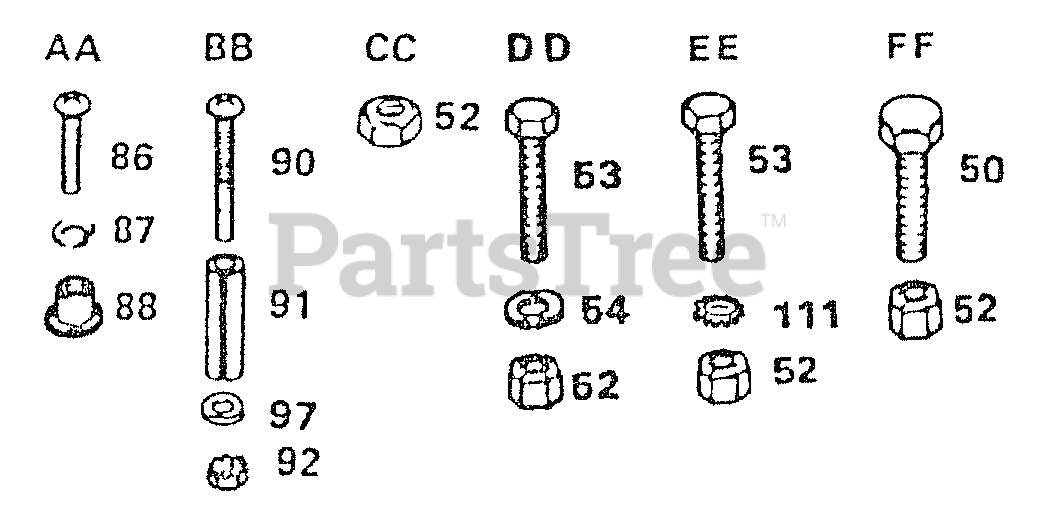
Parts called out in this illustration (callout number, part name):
50	Bolt - Hex 3/8 -16 x 3/4
52	Nut - Crownlock 3/8 - 16
53	Bolt- Hex 3/8 - 16 x 1
54	Washer 13/32 X 1 X 16 Ga.
86	Screw - Cross Recess Pan Hd. Machine 10-24 x 1/2
87	Washer- Lock, No. 10
88	Nut - Weld
90	Screw - Machine Cross Recess 10 - 24 x 1-1/4
91	Spacer- Split 10 x 3/4
92	Nut - Keps 10-24
97	Washer 7/32 x 1/2 x 18 Ga.
111	Lock Washer 3/8 Ext. Tooth
